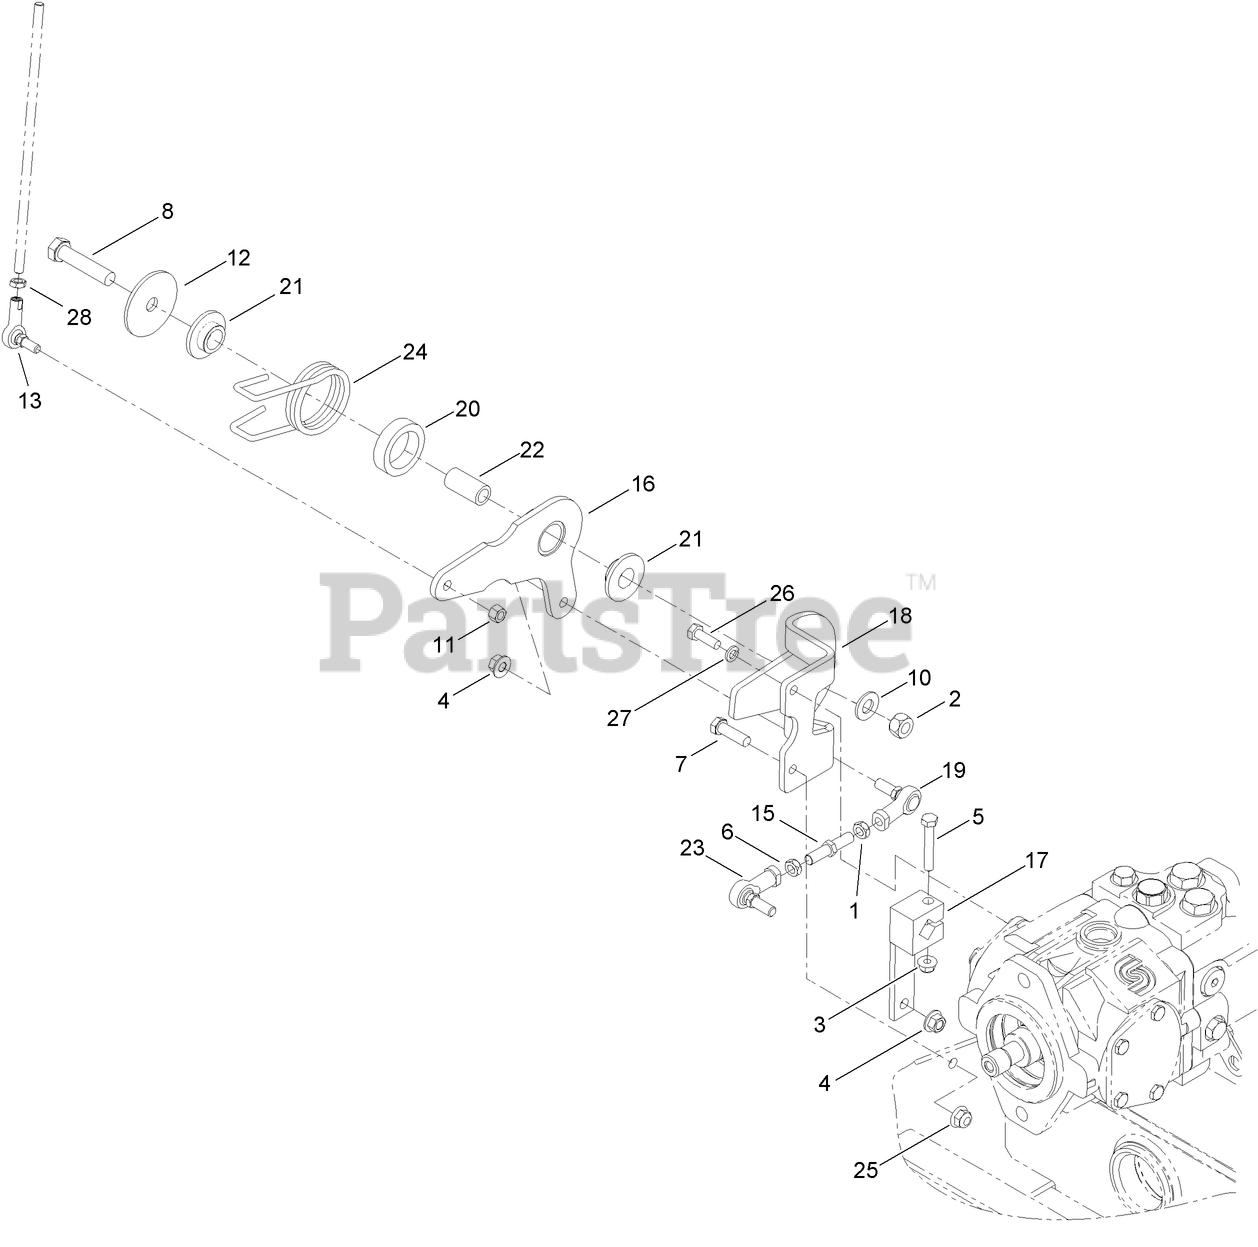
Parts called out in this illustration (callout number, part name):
1	NUT-JAM, LH
2	NUT-LOCK, HEX
3	NUT-HF, NI
4	NUT-FLANGE, LOCK
5	SCREW-HH
6	NUT-JAM, HEX
7	BOLT
8	SCREW-HH
10	WASHER-FLAT
11	NUT-HEX
12	WASHER-FLAT (SPECIAL)
13	JOINT-BALL, LH (FEMALE)
15	SCREW-JACK, CONTROL
16	PLATE-LINKAGE
17	LEVER-CONTROL, PUMP
18	PLATE-PUMP
19	JOINT-BALL, STUD (ROD END)
20	SPACER-COLLAR
21	BUSHING-INSERT, PLASTIC
23	JOINT-BALL
25	NUT-HF, NI
26	SCREW-HH
27	WASHER-LOCK
28	NUT-JAM
